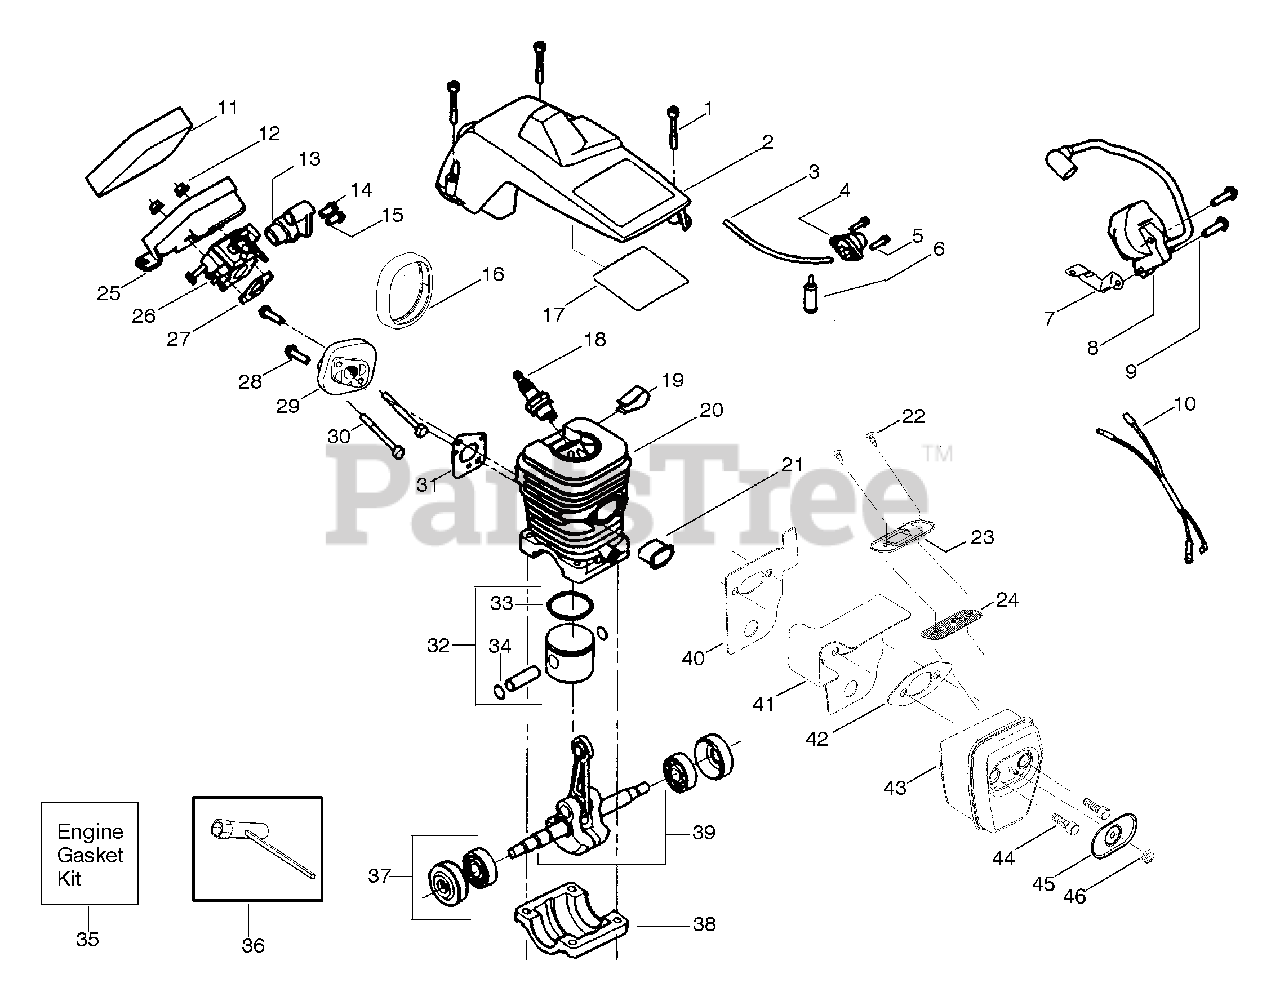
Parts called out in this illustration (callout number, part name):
2	Assy-Cylinder Shield
3	Kit-Fuel Line (Small)
4	Assy-Air Purge
6	Assy-Fuel Pick-up
7	Strap-Ground
8	Ignition Module
10	Assy-Wire Harness
11	Foam-Air Filter
13	Grommet-Carb Adjust
14	Limiter Cap-High
15	Limiter Cap-Low
16	Seal-Carb Adapter
17	Reflector-Heat
18	Spark Plug (RCJ-7Y)
19	Clip- High Tension Lead
20	Kit- Cylinder
21	Insulator- Heat
22	Screw-Outlet cover
23	Cover-
24	Kit-Spark Arrestor
25	Air Filter Housing
26	Kit-Carburetor (WT600)
27	Gasket-Carb.
29	Carb. Adapter
31	Gasket-Carb Adaptor
32	Kit-Piston
33	Ring-Piston
34	Retainer-Piston Pin
35	Kit-Engine Gasket
36	Bar Wrench
37	Assy-Seal & Bearing
38	Cap-Crankcase
39	Assy-Crankshaft
40	Backplate
41	Guide-Outlet
42	Gasket-Muffler
43	Assy-Muffler
44	Bolt-Muffler
45	Cover-Bolt
46	Nut-Brass
